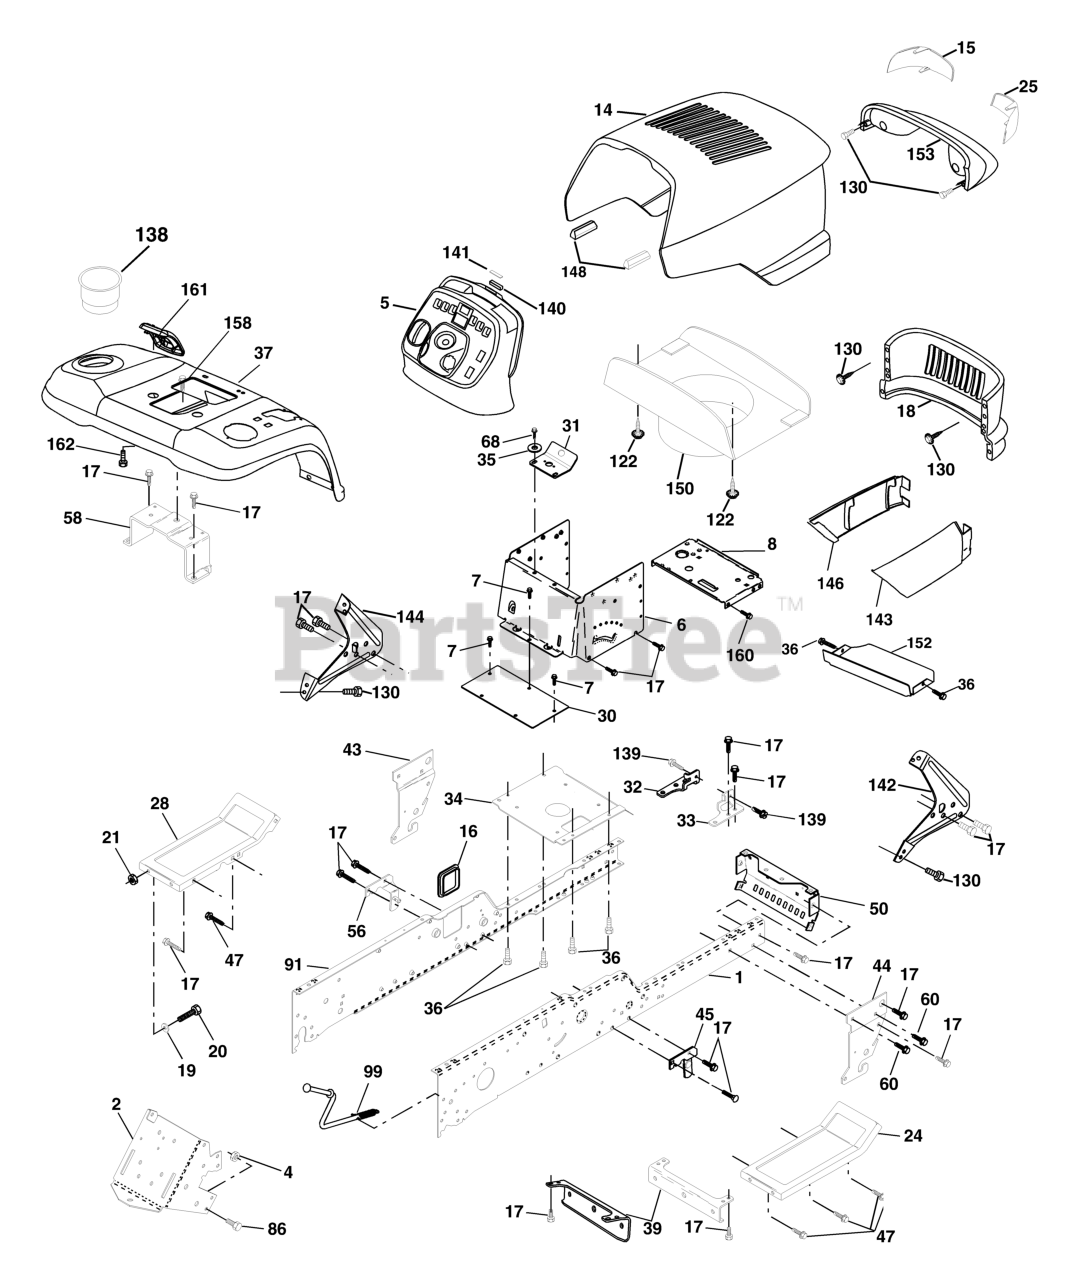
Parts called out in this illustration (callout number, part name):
1	FRAME RAIL RH
2	DRAWBAR, GT
4	Nut, Lock Hex 7/16-14 Unc
5	DASH.STEALTH.YTGT.2CYL.BLK
6	DASH VGT, LOWER
7	SCREW
8	SUPPORT, BATTERY
14	HOOD ASM.
15	LENS RH
16	COVER ACCESS
17	SCREW 3/8-16X3/4
18	GRILLE
19	WASHER
20	BOLT
21	NUT
24	FOOTREST PNT RH
25	LENS LH
28	FOOTREST PNT LH
30	SADDLE.HYDRO.95
31	BRACKET SUPT 1-PC VGT STEERING
34	PLATE ASM ENG CHASSIS
35	WASHER
36	SCREW 5/16"
37	FENDER, PNT
39	BRACKET AXLE, FRONT
43	FRONT SUSPENSION BRKT LH
44	FRONT SUSPENSION BRKT RH
45	BRACKET, ASM., SUSP CHASSIS RH
47	SCREW LT
50	BRACKET, CHASSIS FRONT
56	BRACKET ASM., SUSP CHASSIS LH
58	BRACKET ASM, FENDER
60	SCREW.3/8-16
68	Screw, 5/16-18 x 1/2
86	BOLT FIN HEX 7/16-14 X 1
91	FRAME RAIL LH
99	ROD ASM, BYPASS
122	SCREW.HEX.WS.HD.8-18 X 7/8
130	SCREW
138	CUPHOLDER
139	BOLT, SHOULDER 5/16-18
140	MAGNET STEALTH
141	STRIKER PLATE
142	BRACKET DASH STEALTH(R)
143	SKIRT GRILLE RH
144	BRACKET DASH STEALTH LH
146	SKIRT GRILLE LH
148	EXTRUSION BUMPER (3 2) (2 2)
150	DUCT HEAT HOOD
152	BROWNING SHIELD
153	Lens, Headlight Bar
158	SCREW 3/8-16X1/2
160	SCREW 5/16-18X1/2"
161	CONSOL.FUEL.WINDOW.BLACK
162	SCREW.HI-LO.CONSOLE
